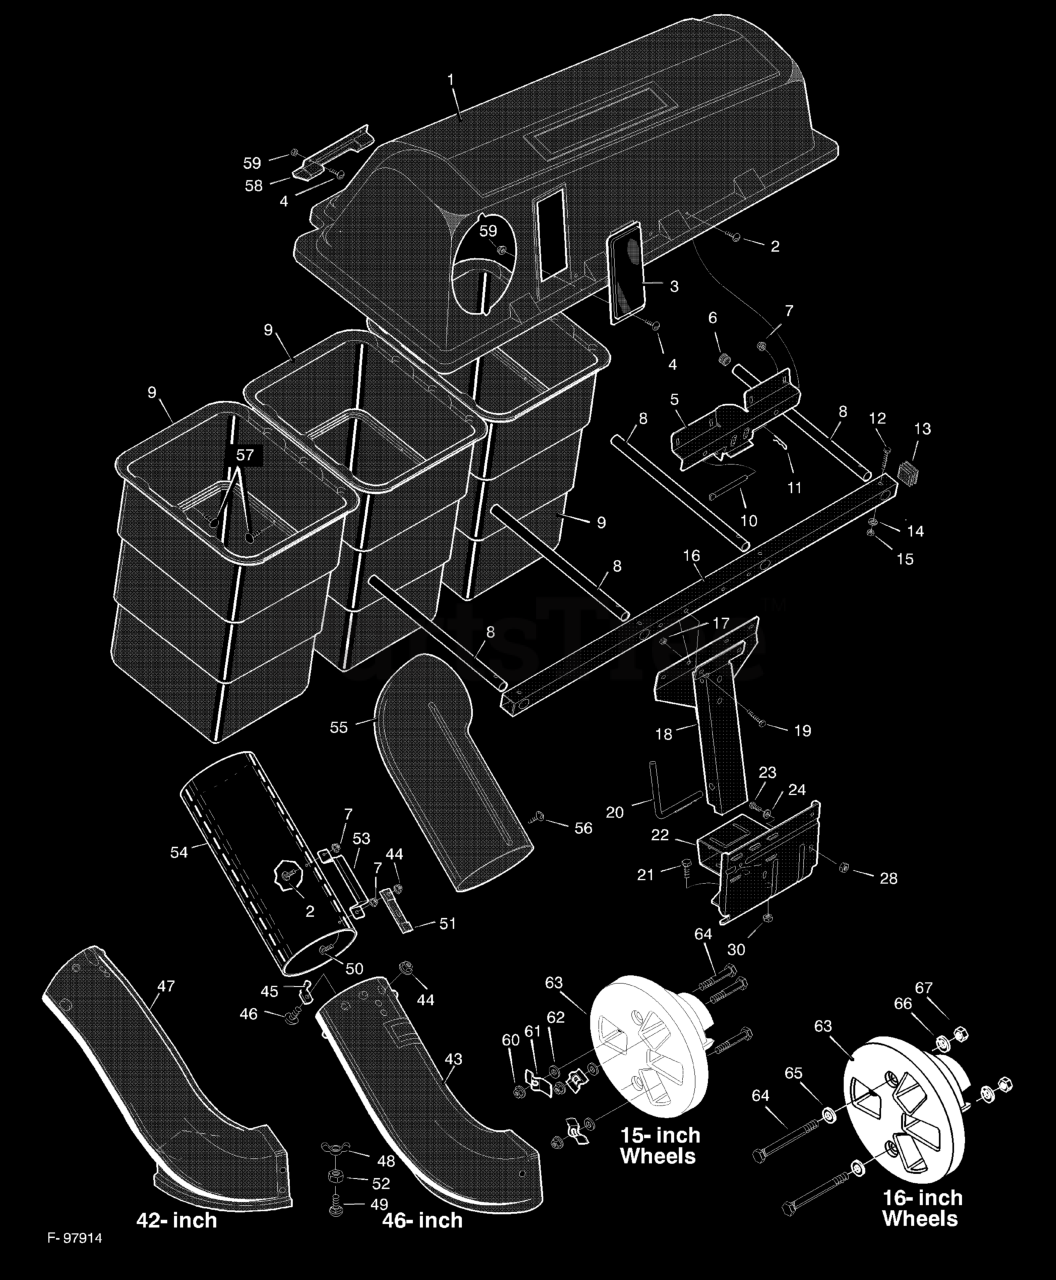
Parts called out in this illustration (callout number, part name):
1	Cover, Bagger
5	Hinge, Bracket
7	Nut, Hex
8	Tube, Container
9	Container
10	Pin, Cover Hinge
11	Pin, Hair
13	Plug
14	Lockwasher
16	Tube, Support
17	Nut
18	Assembly, Channel
20	Pin, Channel Mount
21	Bolt, Hex
22	Assembly, Bagger Mount
23	CAPSCREW, Hex Head, 5/16-18 x 1
28	Nut, Super Flange
30	Nut, Hex
43	Extension, Chute
44	Locknut, Flange
45	Pin, Latch
46	Bolt, Carriage
47	Extension, Chute
48	Wingnut
49	Bolt, Carriage
51	Latch, Rubber
53	HANDLE, Connect Tube
54	Tube, Connecting
57	Fastener, Panel
58	Handle, Plastic
59	Nut, Hex
60	Nut, Flange
61	Clip, Wheel
62	Retainer
63	Weight, Wheel
66	Washer
